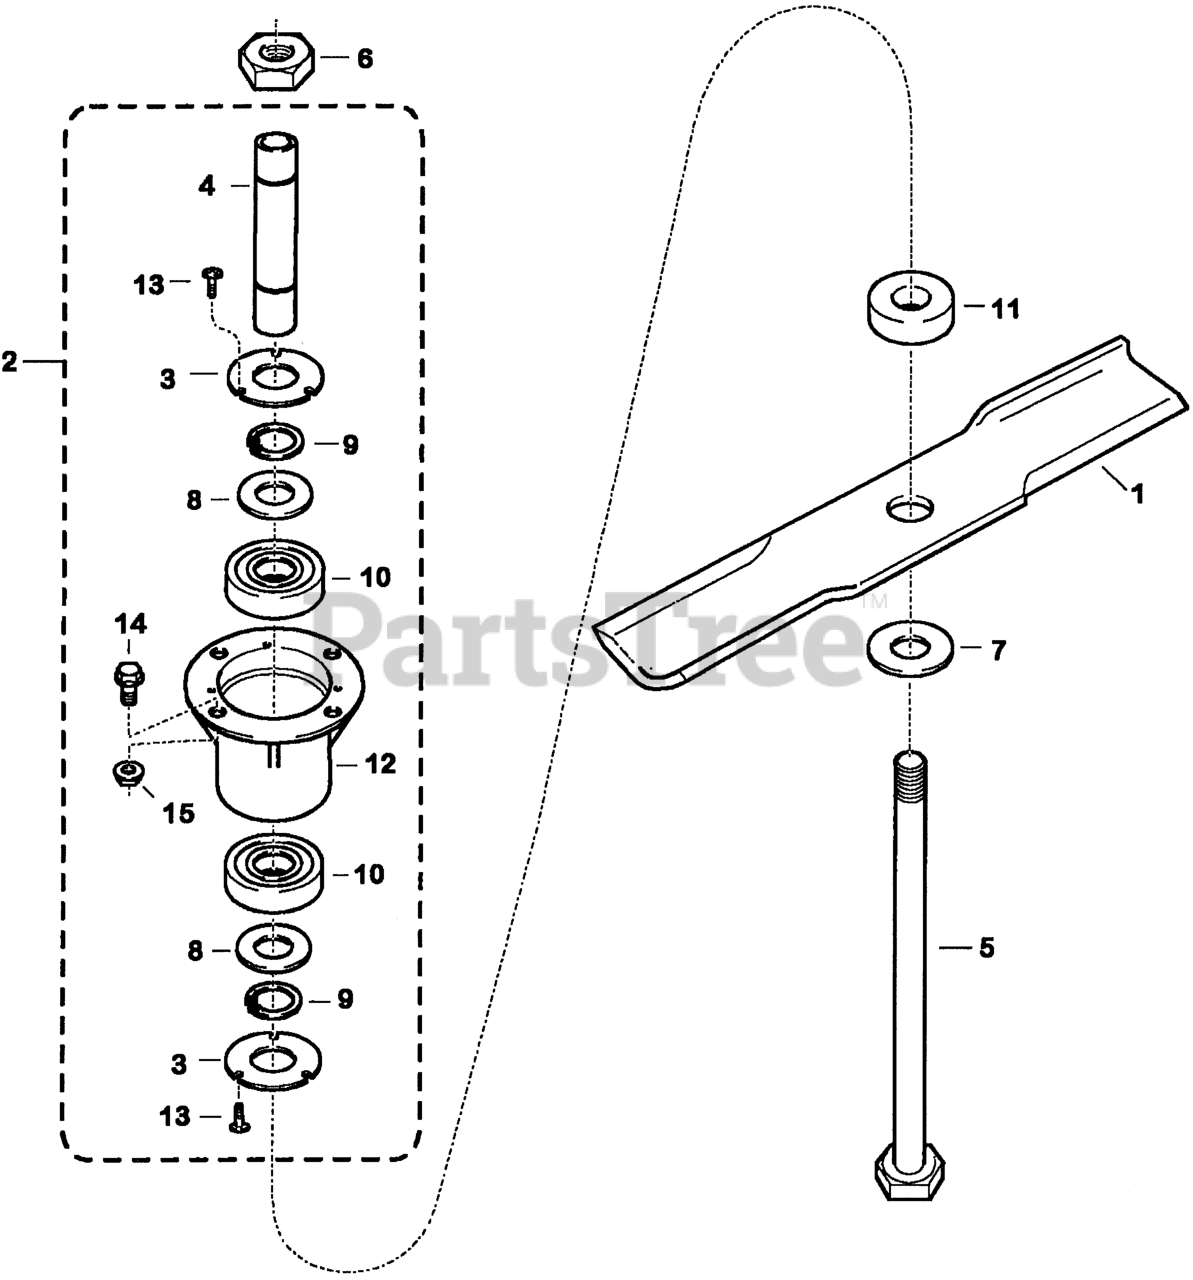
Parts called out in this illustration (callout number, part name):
1	BLADE, HIGH LIFT (16.5")
2	HOUSING ASSY., BLADE BEARING
3	CAP, BEARING HOUSING
4	SHAFT, BLADE
5	BOLT, BLADE
6	JAM NUT (5/8"-18)
7	WASHER, BLADE
8	WASHER, SLINGER
9	RING, SNAP
10	BEARING, BLADE SHAFT
11	COLLAR, BLADE (5/8")
